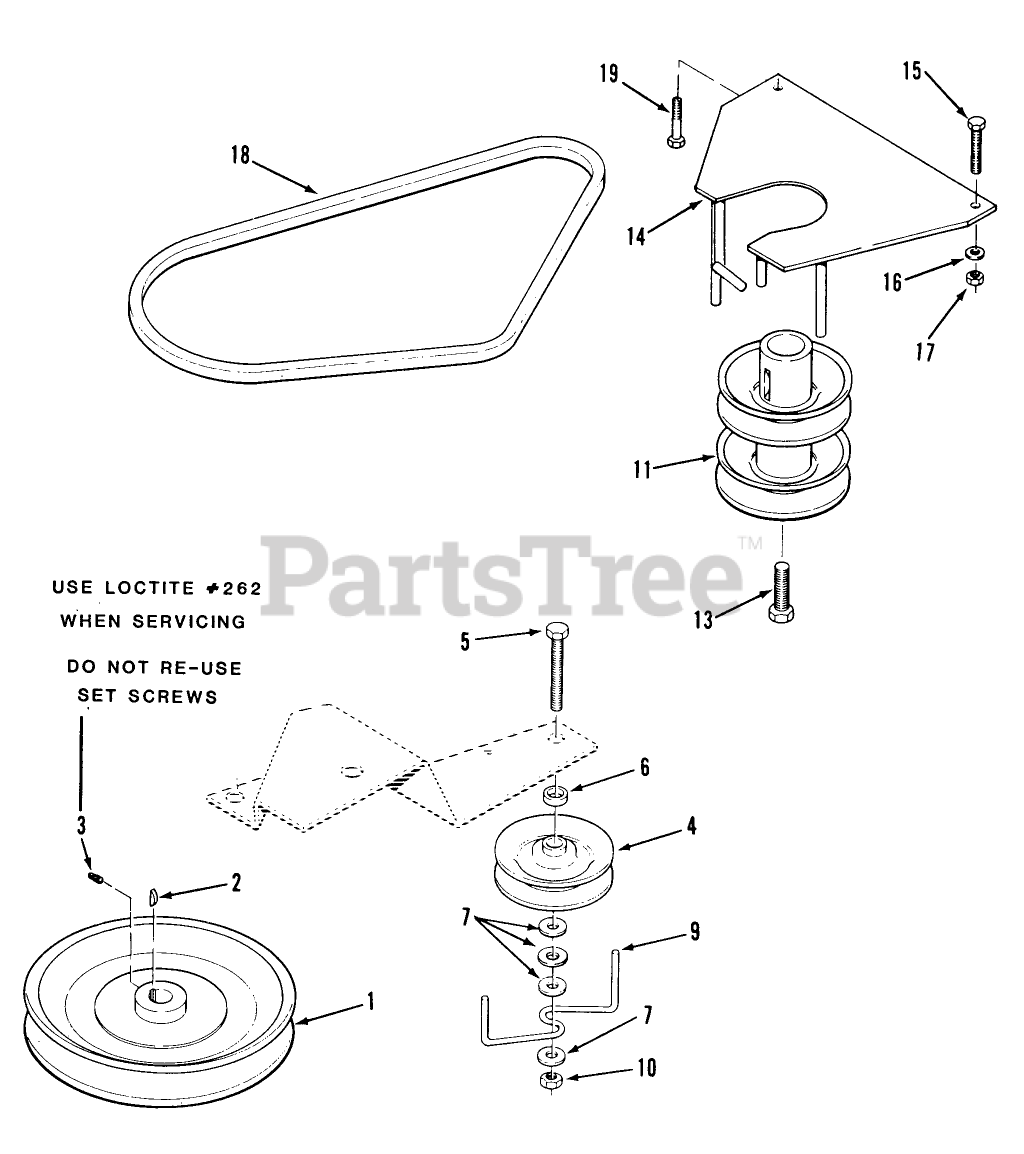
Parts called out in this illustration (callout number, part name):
1	PULLEY TRANSMISSION
2	KEY-HI-PRO
4	PULLEY-IDLER V
6	SPACER
9	GUIDE - BELT
10	NUT-HEX, JAM
14	ASS'Y-BELT GUIDE *R
16	WASHER 5/16 SAE
18	BELT-V
